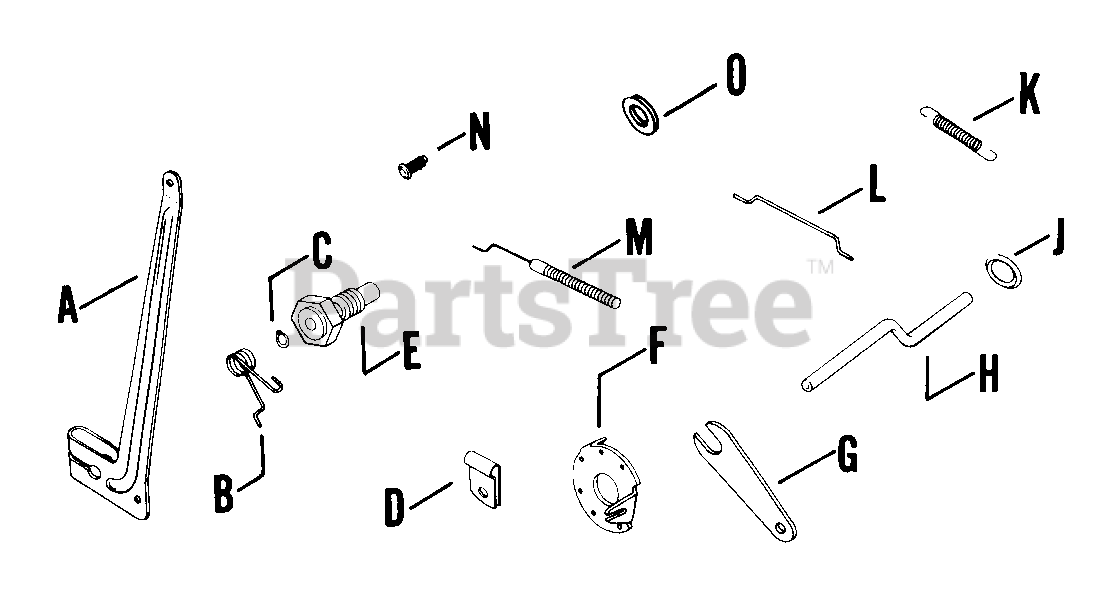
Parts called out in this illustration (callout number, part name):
A	ARM - DISCONTINUED
B	SPRING - DISCONTINUED
E	BUSHING - (#DSC)
F	DISC, GOVERNOR REGULATING
G	BRACKET, SUPPORT - DISC.
H	SHAFT - DISCONTINUED
L	LINKAGE
N	SCREW, DRIVE USE 25 086 86-S
